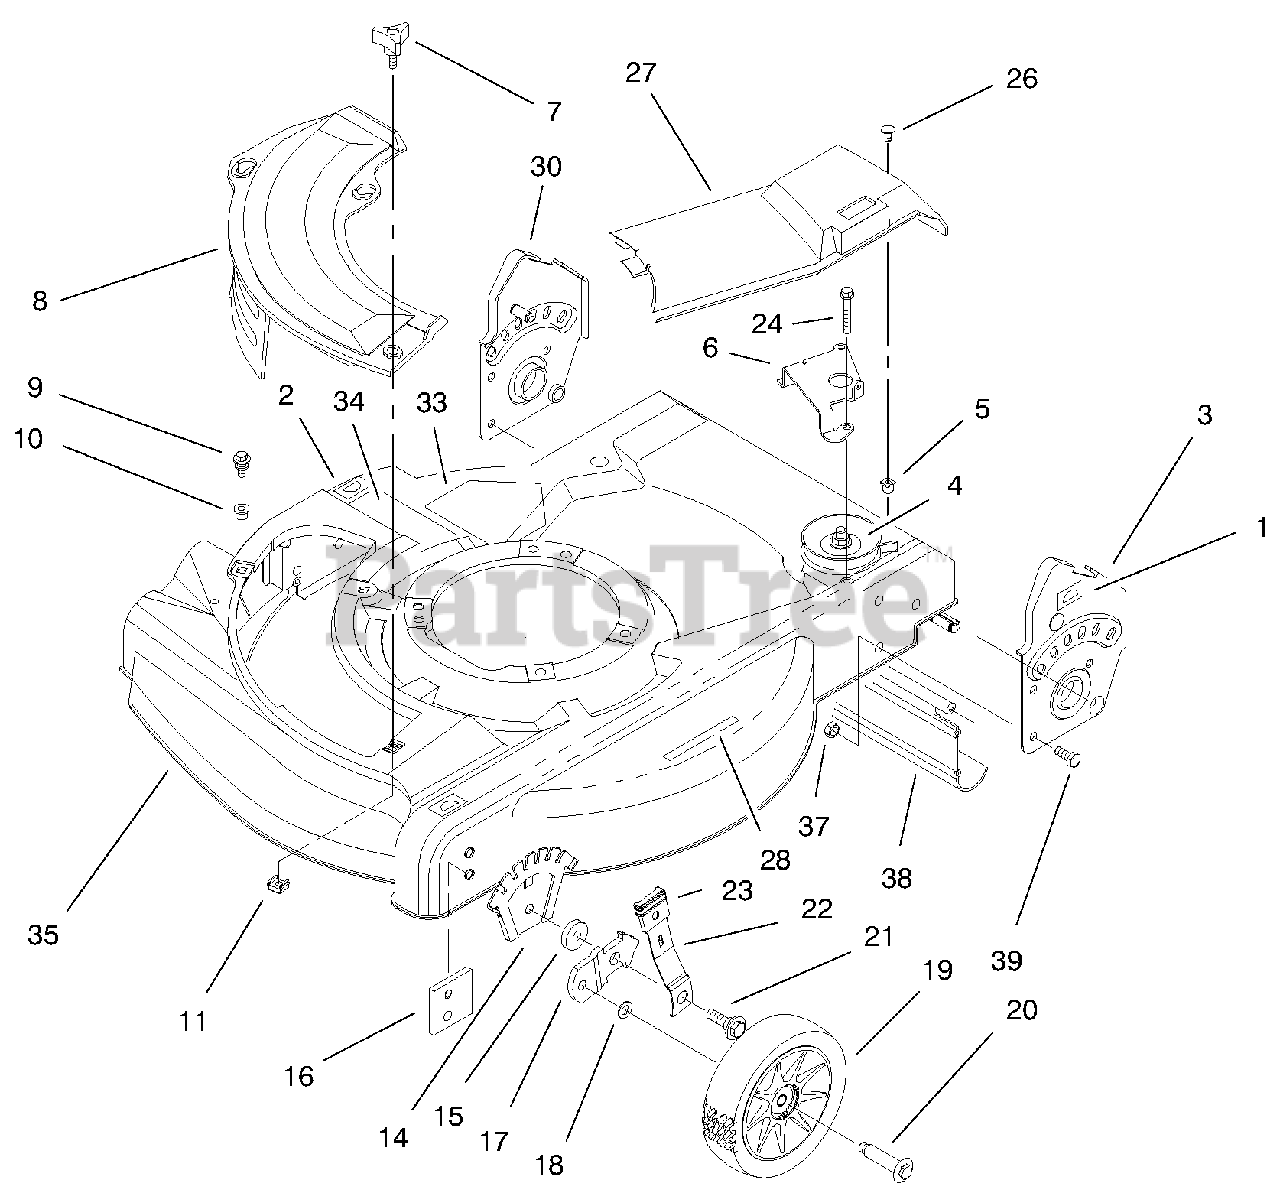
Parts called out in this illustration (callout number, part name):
1	Decal-H.O.C.
2	Decal-H.O.C.
3	Bracket-Handle L.H.
4	Gear Case Assembly
5	Grommet
6	Guide-Transmission
7	Knob-Cover Plate
8	Plate-Mulch 21"
9	Screw-Sems Thr'd Form.
10	Grommet-Plastic
11	Nut-Cage
14	Plate-Height Adjust
16	Plate-Baffle
17	Bracket-Wheel Height Adj.
19	Wheel & Tire Assembly-6"
20	Bolt-Shoulder
21	Bolt-Shoulder
22	Spring Arm-Front
23	Knob-Height Adjust
24	Screw-Hex Hd. Cap
26	Screw-Phillip Hd.
27	Cover-Drive
28	Decal-Warning
30	Bracket-Handle R.H.
33	Decal-Danger
34	Decal-Discharge
35	Housing Assembly (Incl. Ref. #5, 10, 11, 28, 33, & 34)
37	Nut-Hex Lock
38	Shield-Trailing
39	Screw-Hex Hd. Cap
